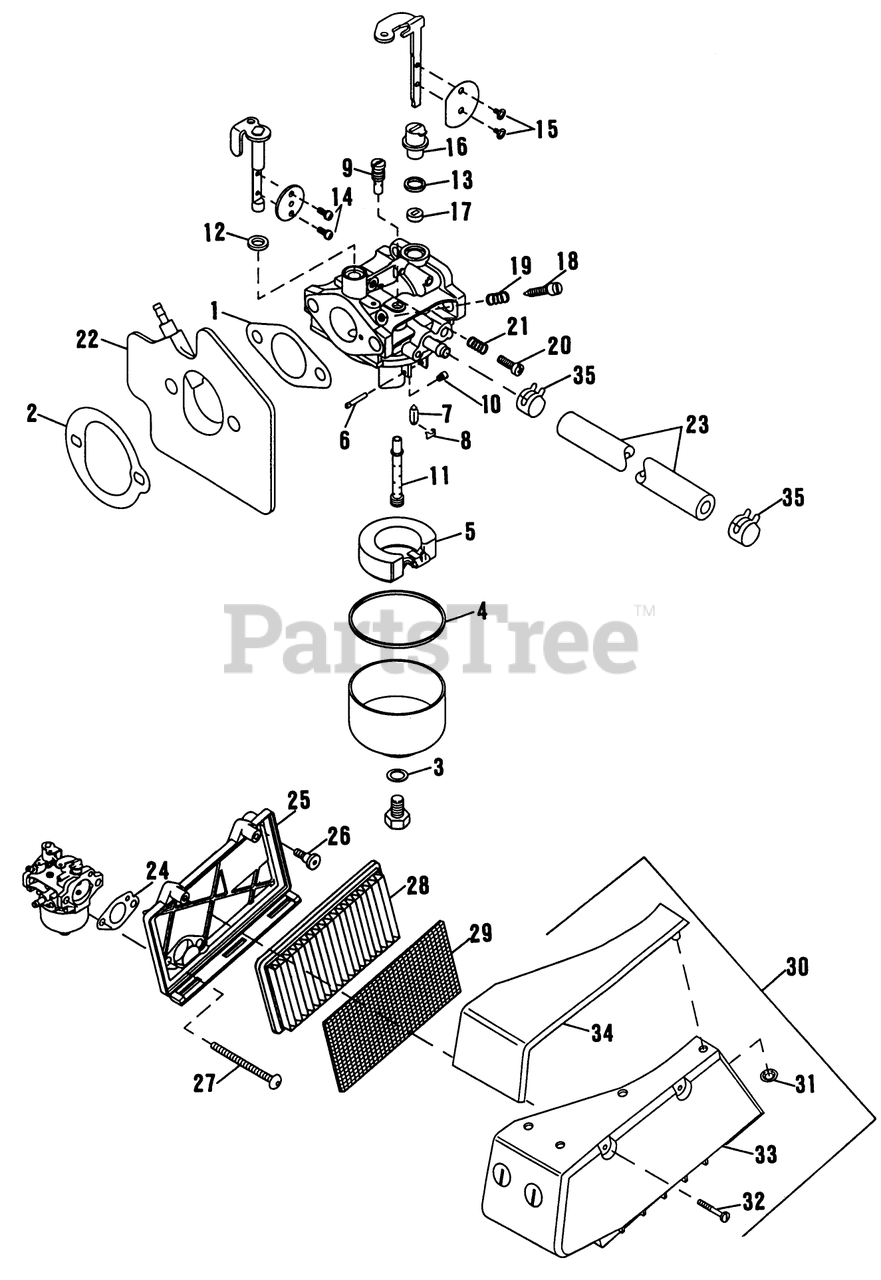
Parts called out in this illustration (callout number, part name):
1	GASKET SM
2	GASKET SM
3	GASKET-BOWL RET S
4	GASKET-FUELBOWL S
6	Shaft-Float
8	CLIP S
9	PILOT JET
13	SEAL CHOKE SHAFT
15	SCREW CHOKE VALVE
22	SPACER & NOZZ SM
23	GAS LINE SM
24	GASKET-FIL SM
28	ELEMENT-AIR SM
31	NUT-PUSH
35	HOSE CLAMP SM
36	MAIN JET
